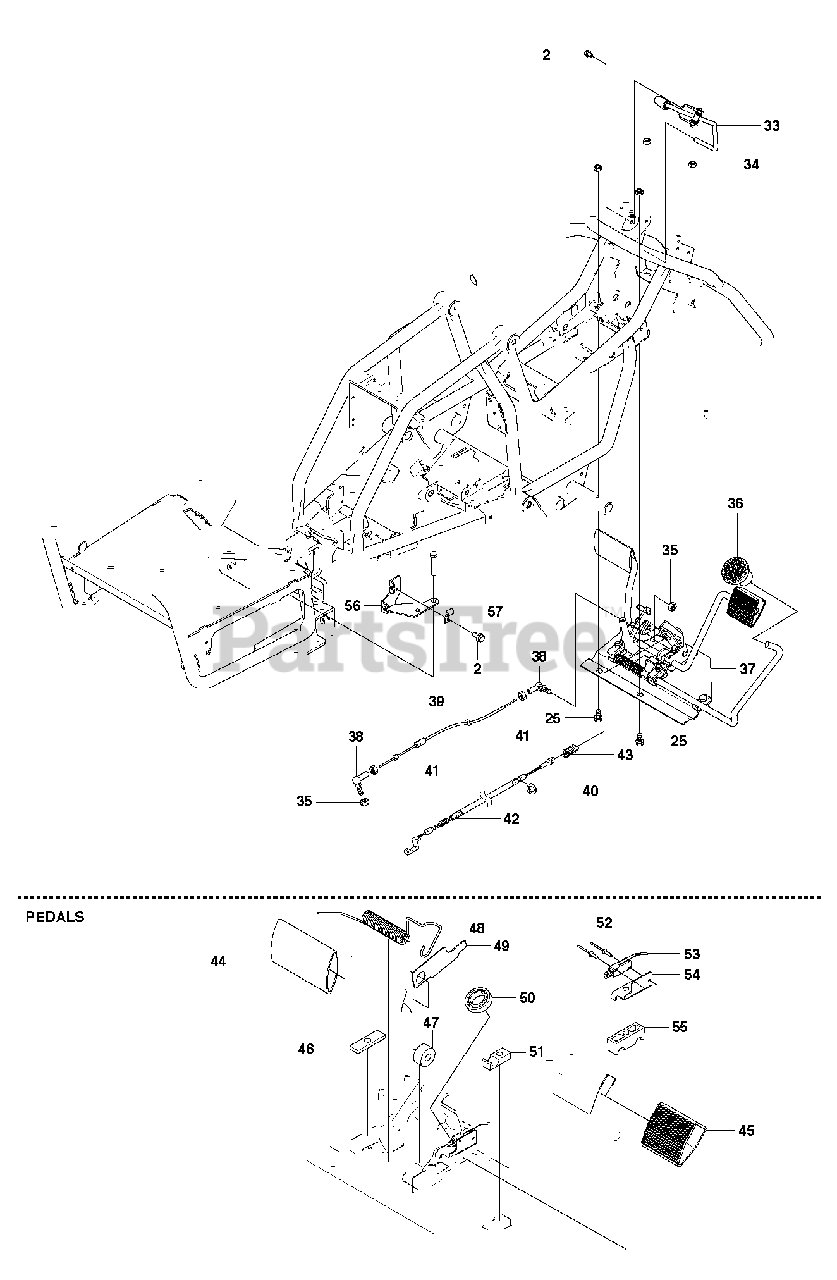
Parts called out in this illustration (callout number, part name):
36	KNOB
37	PEDAL ASSEMBLY
38	CONNECTOR
41	LOCKNUT M5
44	PEDAL RUBBER, SF
45	PEDAL RUBBER
46	PLATE
47	ROLLER
48	SPRING
49	PLATE
50	BALL BEARING 6002-2RS1
51	SUPPORT
53	MICRO SWITCH
55	PEDAL SHAFT CLAMP
